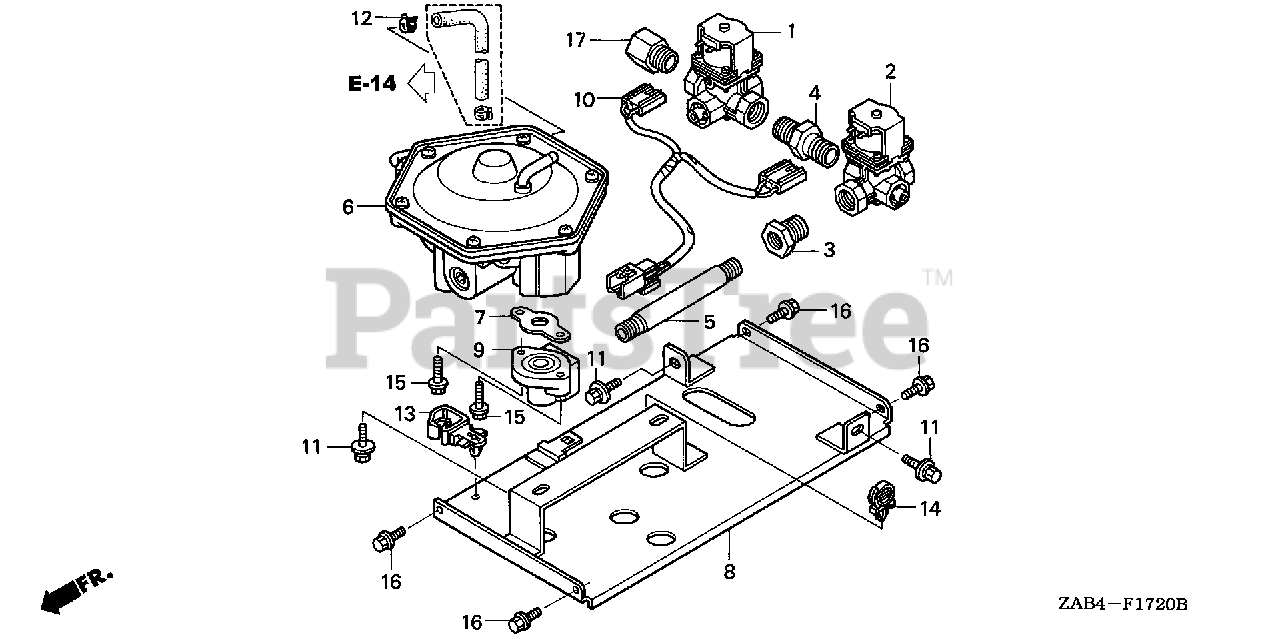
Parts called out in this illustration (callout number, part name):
1	VALVE ASSY., SOLENOID (A)
2	VALVE ASSY., SOLENOID (B)
3	BUSHING (1/2X3/8)
4	NIPPLE (1/2)
5	JOINT, IN. PIPE
6	REGULATOR, LOW PRESSURE
7	GASKET, ZERO GOVERNOR
8	STAY, ZERO GOVERNOR
9	PIPE, INLET
10	HARNESS ASSY., SOLENOID VALVE
11	BOLT-WASHER (6X16)
12	CLIP, FUEL HOSE
13	CLIP, HARNESS (5MM-15MM)
14	CLIP, WIRE HARNESS
15	BOLT-WASHER (6X25)
16	BOLT, FLANGE (6X10)
17	ADAPTER (1/2X1/2)
